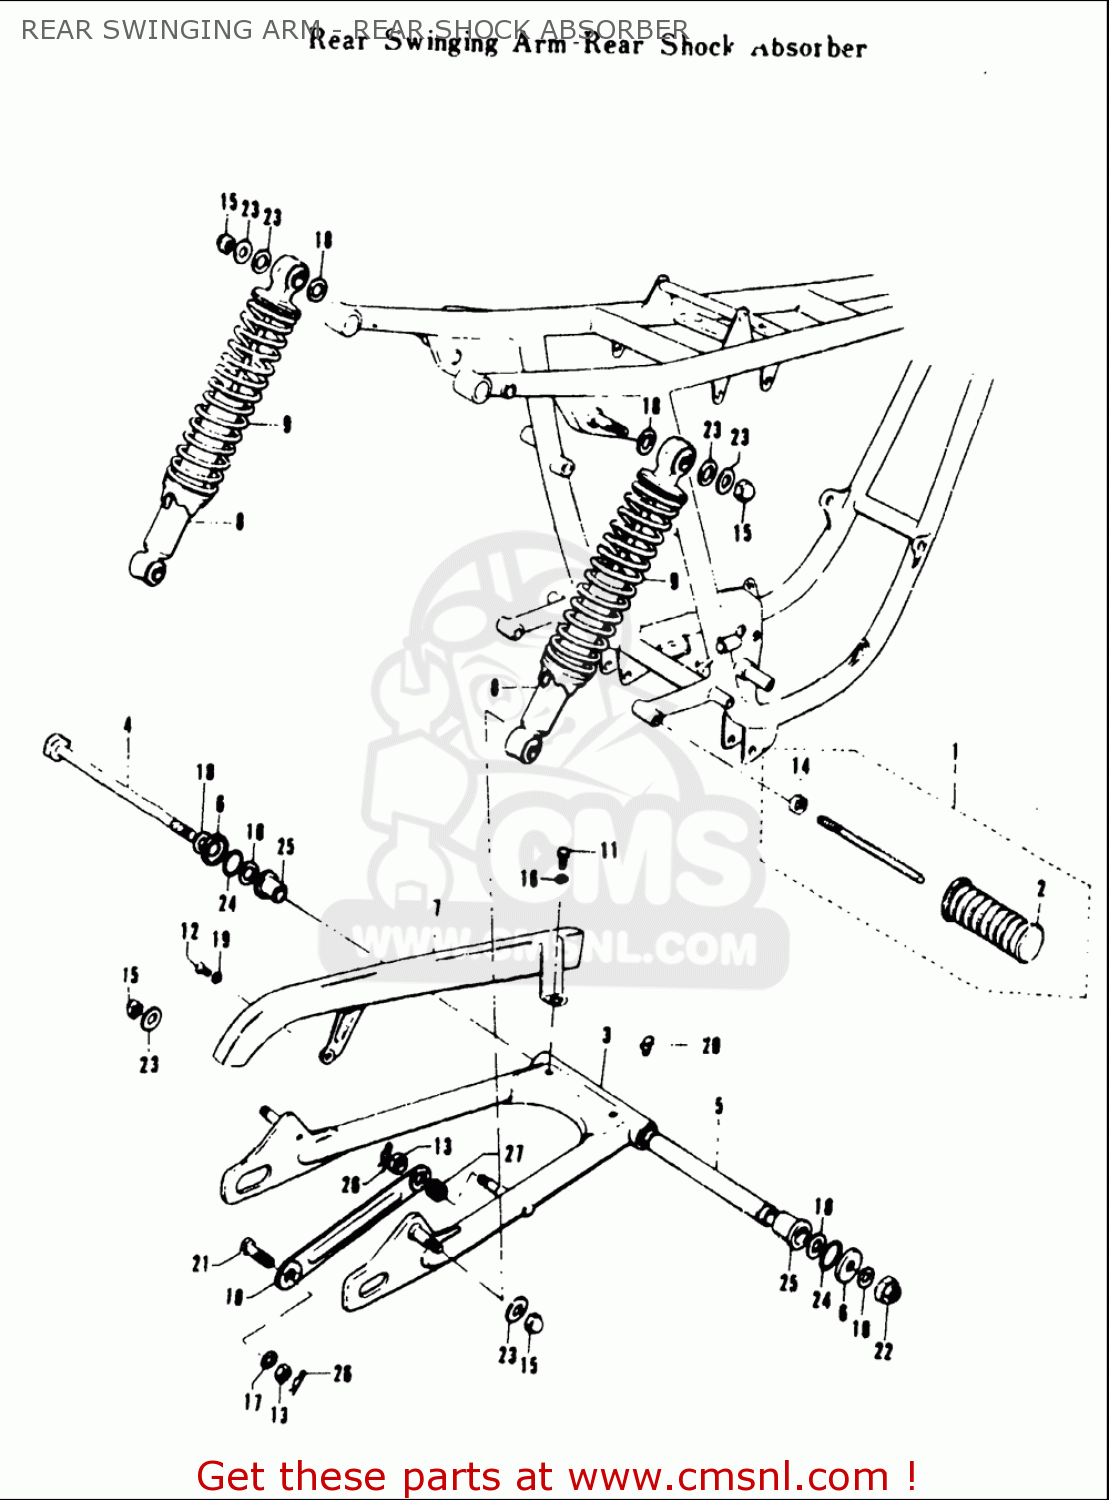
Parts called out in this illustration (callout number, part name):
1	FOOTREST SET,PILLION
2	FOOTREST SET,PILLION
6	COVER,SWGARM BUSH DUST SEAL
13	NUT
14	NUT
15	NUT
16	WASHER,LOCK
17	WASHER,LOCK
18	WASHER
19	TOOTHED WASHER
20	NIPPLE,GREASE
21	BOLT(10X31)
22	NUT
23	WASHER (10.5X24X2.3)
24	O RING(D:2,ID:24.5)
26	CLIP
27	SPRING
